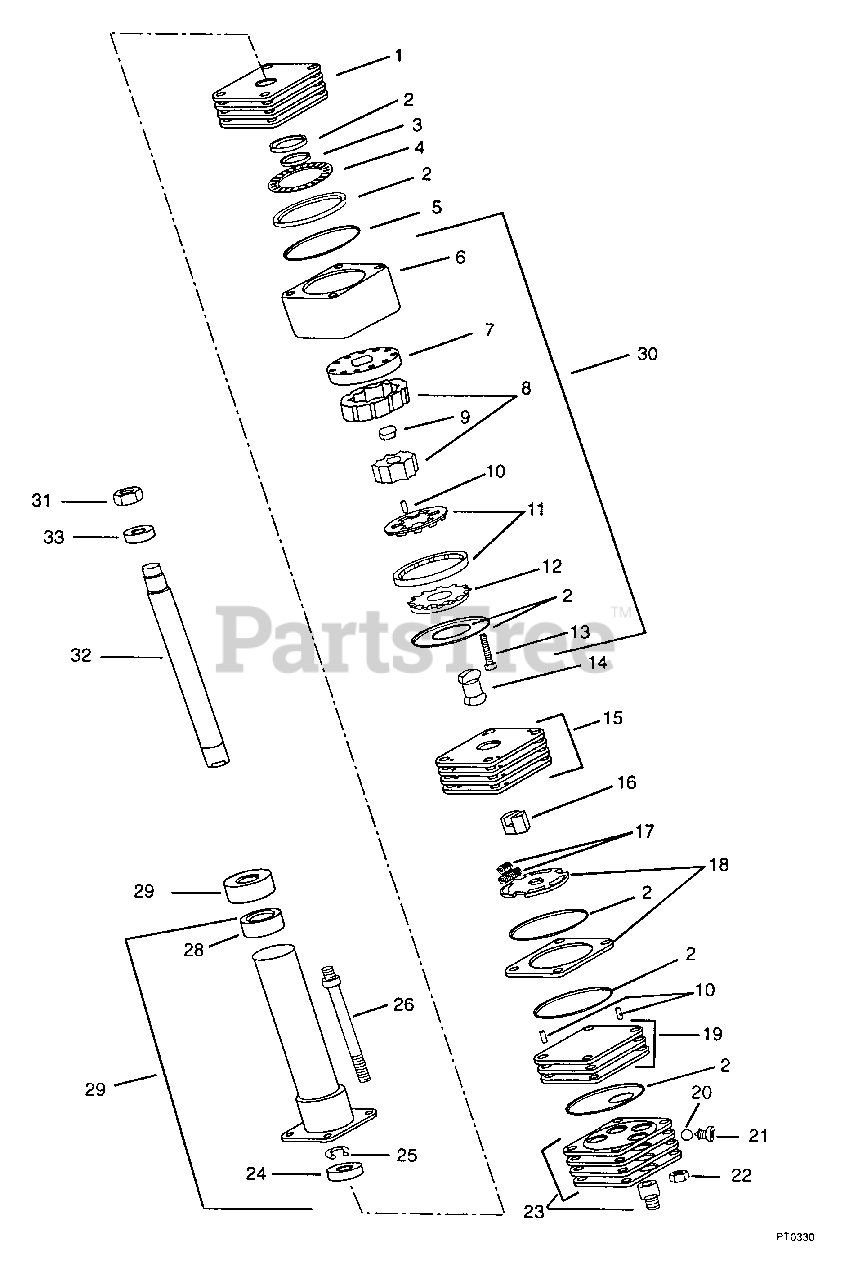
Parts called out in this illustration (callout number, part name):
1	UPPER COVER PLATE
2	SEAL SERVICE ASS'Y
3	SEAL SPACER
4	THRUST BEARING
5	SPACER-ROSS SERVICE
6	METERING RING
7	DRIVE PLATE
9	SPACER-ROSS SERVICE
10	NEEDLE ROLLER SERVICE ASS'Y
11	COMMUTATOR & RING ASS'Y
12	COMMUTATOR COVER
13	SCR-SPECIAL ROSS
14	DRIVE LINK
15	ISOLATION MANIFOLD
16	HEX DRIVE
17	SPRING SERVICE ASS'Y
18	VALVE & RING ASS'Y
19	PORT MANIFOLD
20	BALL - STEEL
21	PLUG & O-RING ASS'Y
22	NUT-LK-CTR .312-24 PL
23	PORT COVER
25	RG-RTNG ROSS #401465
26	STUD-SPECIAL SV ROSS
27	INPUT SHAFT SERVICE ASSEMBLY
28	COLUMN BEARING SET
30	METERING ASS'Y
31	NUT-LK-JAM .625-18 YWZC
32	UPPER COVER & JACKET TUBE ASSY
33	DUST COVER
